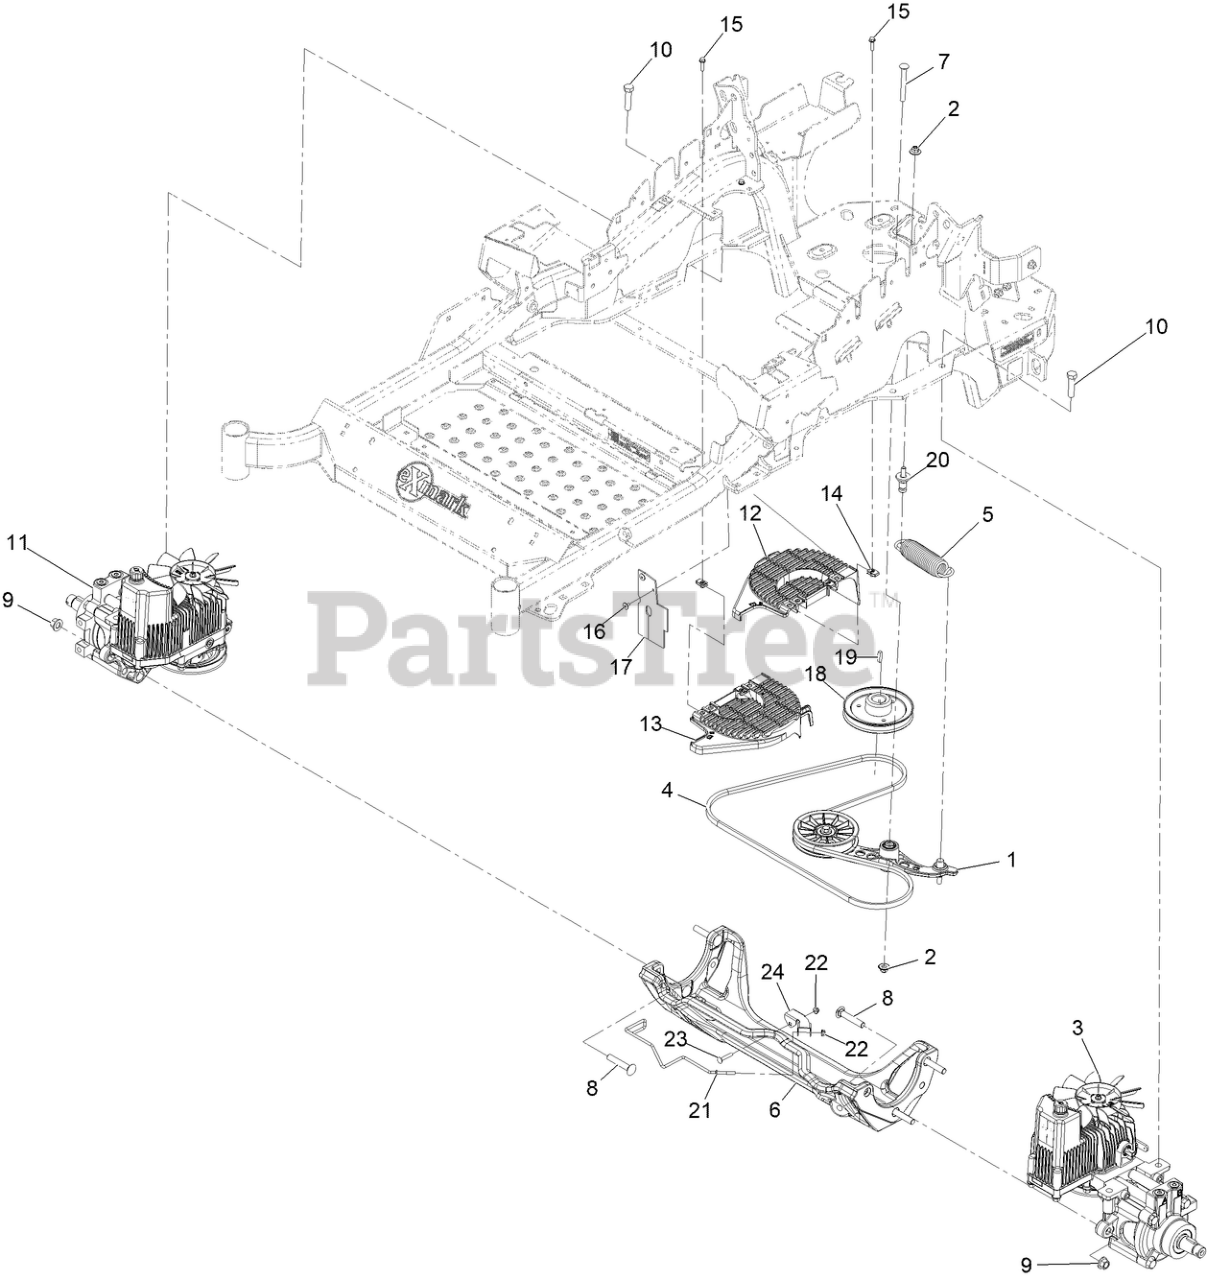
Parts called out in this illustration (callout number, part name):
1	PUMP IDLER ASM
2	Nut-Nyloc 3/8-16 Flg
3	HYDRO-LH
5	SPRING-EXTENSION
6	CRADLE-HYDRO
7	BOLT-SHOULDER, CARRIAGE 3/8-16 X 3 1/2
8	SCREW-CARR
9	Nut-Lock 1/2-13
10	SCREW-HH
11	HYDRO-RH
12	Cover-Fan, Lt
13	Cover-Fan, Rt
15	SCREW-HHF
16	RIVET-POP
17	DEFLECTOR-AIR FLOW
18	SHEAVE, W/HUB
20	Pin-Spring, Anchor
21	Guide-Belt
23	SCREW-CARR
24	Bracket-U
